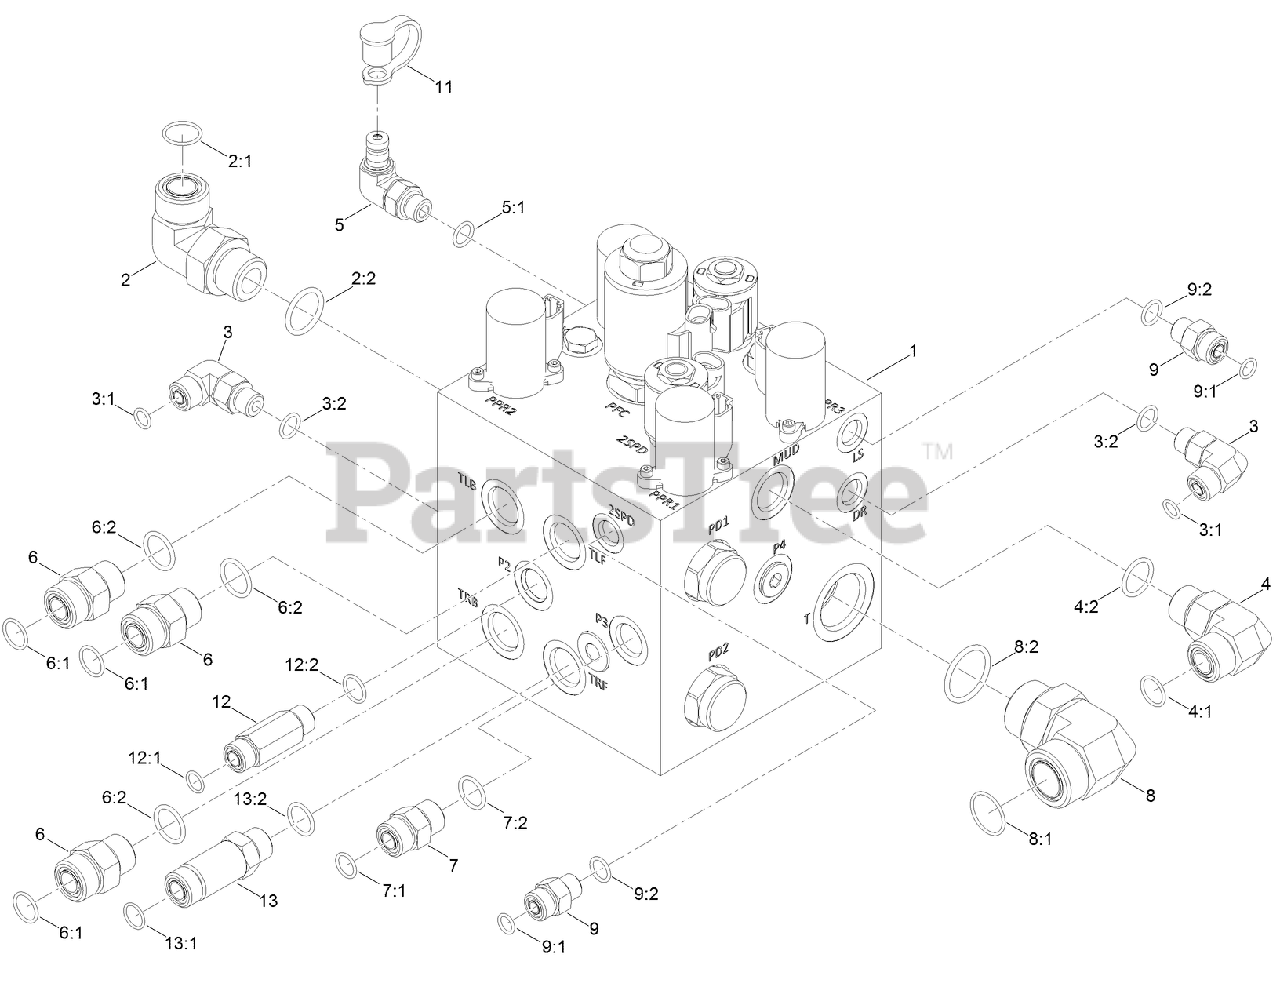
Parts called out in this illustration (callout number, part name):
1	TRACTION MANIFOLD ASM
2	FITTING-ELBOW-90
2:1	O-RING
2:2	O-RING
3	FITTING-ELBOW, 90 DEG
3:1	O-RING
3:2	O-RING
4	FITTING-ELBOW, 90 DEG
4:1	O-RING
4:2	O-RING
5	FITTING-ELBOW-90
5:1	O-RING
6	FITTING-STRAIGHT
6:1	O-RING
6:2	O-RING
7	FITTING-STRAIGHT
7:1	O-RING
7:2	O-RING
8	FITTING-ELBOW, 90 DEG
8:1	O-RING
8:2	O-RING
9	FITTING-STRAIGHT
9:1	O-RING
9:2	O-RING
11	CAP-DUST
12	FITTING-STR
12:1	O-RING
12:2	O-RING
13	FITTING-STR-LONG
13:1	O-RING
13:2	O-RING
